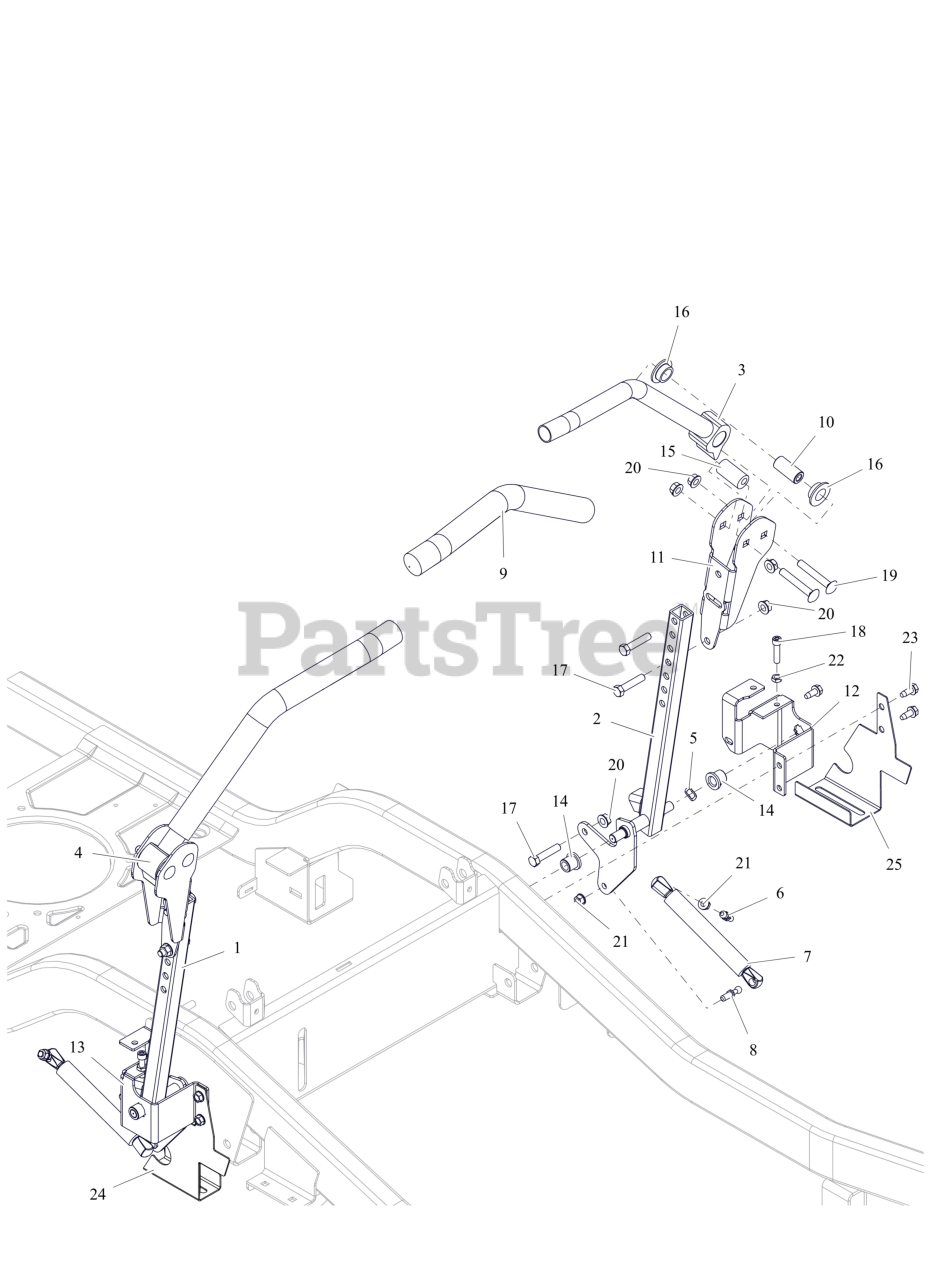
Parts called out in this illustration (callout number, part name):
1	WLDMT, STEERING RH
2	WLDMT, STEERING LH
3	WLDMT, CONTROL HANDLE-LH (BLACK)
4	WLDMT, CONTROL HANDLE-RH (BLACK)
5	WAVE WASHER .531X.781X.125FH
6	STUD- BALL
7	DAMPER
8	STUD-BALL-THREADED
9	GRIP, HANDLEBAR
10	SPACER, STEERING ARM
11	ADJ UPPER CONTROL ARM BRKT-BLK
12	BRKT, STEERING ARM MOUNT -LH
13	BRKT, STEERING ARM MOUNT -RH
14	BHSG-FLG .500X.750X.750X.125
15	BSHG, ECCENTRIC.406X.875X1.625
16	BSHG-FLG .762X1.48X.44 NYL
17	BLT, HEX .38-16X1.75 G5 ZCC
18	BLT, SHCS .312-18X1.25 G8 SS
19	BLT, RHSSN.38-16X2.50 G5 ZCC
20	NUT-LK-TOP-FLG .38-16 ZC120
21	NUT,LK-CTR-FLG .31-18 GF ZCC
22	NUT-JAM .312-18 G2 ZCC
23	SCR,TAP .312-18X.75 HWH TR ZCC
24	GUARD, FRAME RAIL BELT-RH (BLACK)
25	GUARD, FRAME RAIL BELT-LH (BLACK)
